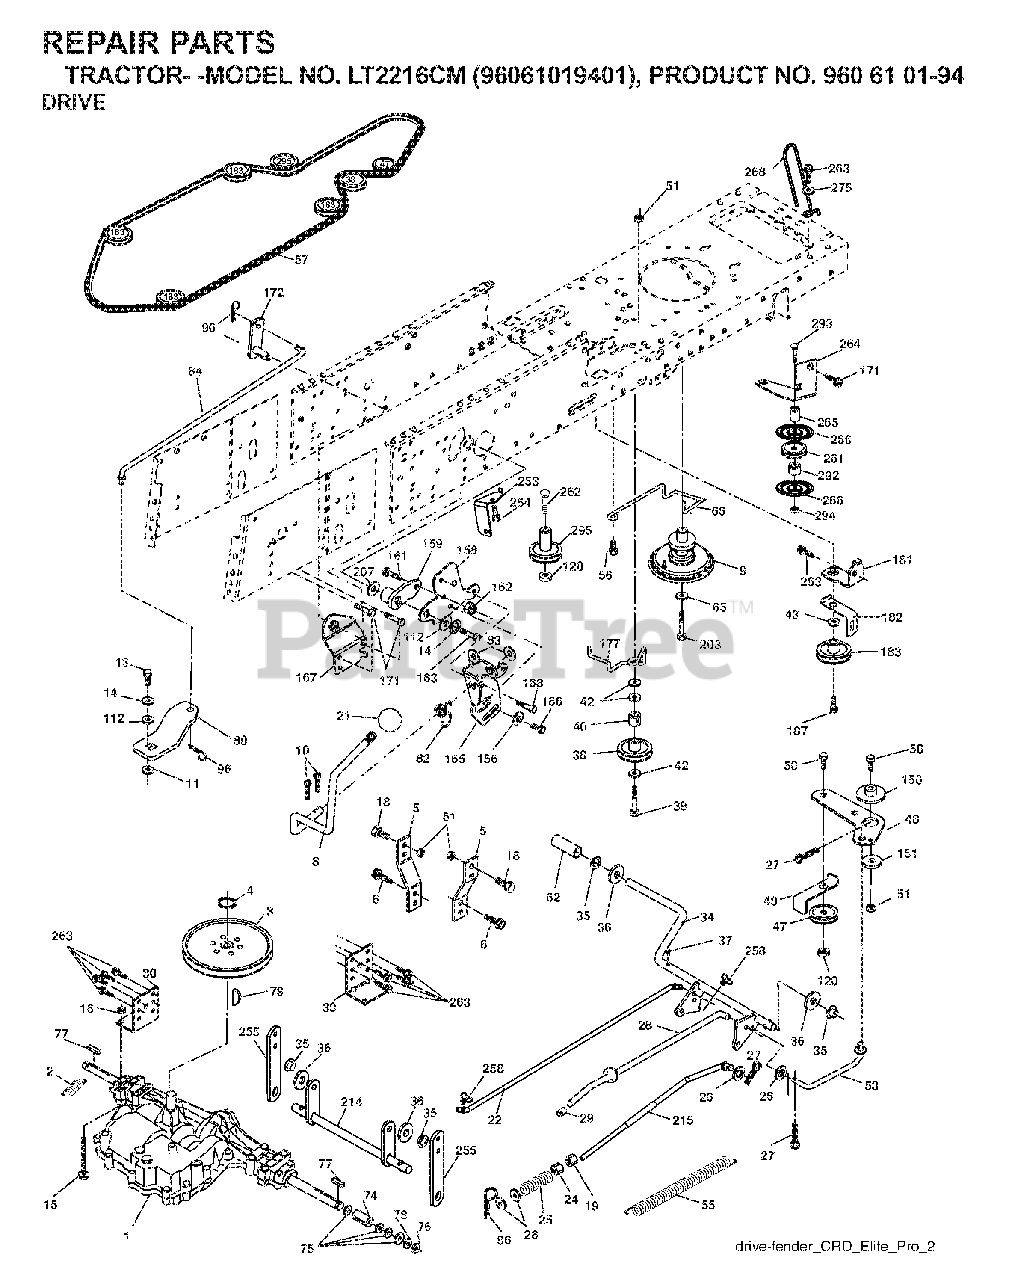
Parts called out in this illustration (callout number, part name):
2	SPRING,BRAKE RETURN
4	RETAINING RING LT
5	STRAP TORQUE
6	SCREW 5/16"
8	ROD SHIFT FENDER ADJUST LT
10	PIN COTTER
11	WASH-SHFT PLT LT
13	BOLT 1/4-28X3/4
14	LOCKWASHER
15	BOLT HEX 5/16-18 GR 5
16	NUT.71038.31-18.HEX.NYLOCK
19	NUT
21	KNOB.DUCKHEAD.1/2
24	NUT
25	SPRING ROD LT
27	COTTER PIN
28	ROD, PARKING BRAKE
29	PLUNGER CAP
30	BRKT, MOUNT TRNSAXLE
34	SHAFT, FOOT PEDAL
35	BEARING.NYLON
36	WASHER LT
37	DRIVE PIN
38	PULLEY.FLAT
42	WASHER
47	IDLER PULLEY
48	BELLCRANK, CLUTCH
49	RETAIN BELT
50	BOLT.3/8-16X1.50
51	LOCKNUT
53	LINK.CLUTCH.7.66.2005
55	SPRING, RETURN LT
56	SCREW.3/8-16
62	PEDAL COVER T
65	LOCKWASHER
66	KEEPER BELT ENGINE
76	E-RING LT
77	SQUARE KEY
80	ARM SHIFT
82	SHIFT SPRING
83	WASHER
96	RETAINER M
112	WASHER LT
120	NUT LOCK FLG 3/8-16 UNC
150	BUSHING.BELLCRANK.GRD.DR
151	WASHER 12/32X2X10GA
156	WASHER.SRRTD.5/16
158	BRACKET
159	HUB.SHIFT
161	BOLT
162	NUT.CROWNLOCK.1/4
165	RP BRACKET
167	BRACKET
168	BOLT.SHOULDER.5/16-18X
187	BOLT.5/16-18X1.25
207	WASHER NYL
254	SCREW 3/8-16X1
258	CLIP RETAINER
261	FLAT IDLER PULLEY
263	SCREW, 3/8-16X3/4
275	WASHER
294	NUT, HEX 3/8-16
295	PULLEY IDLER COMPOSITE
